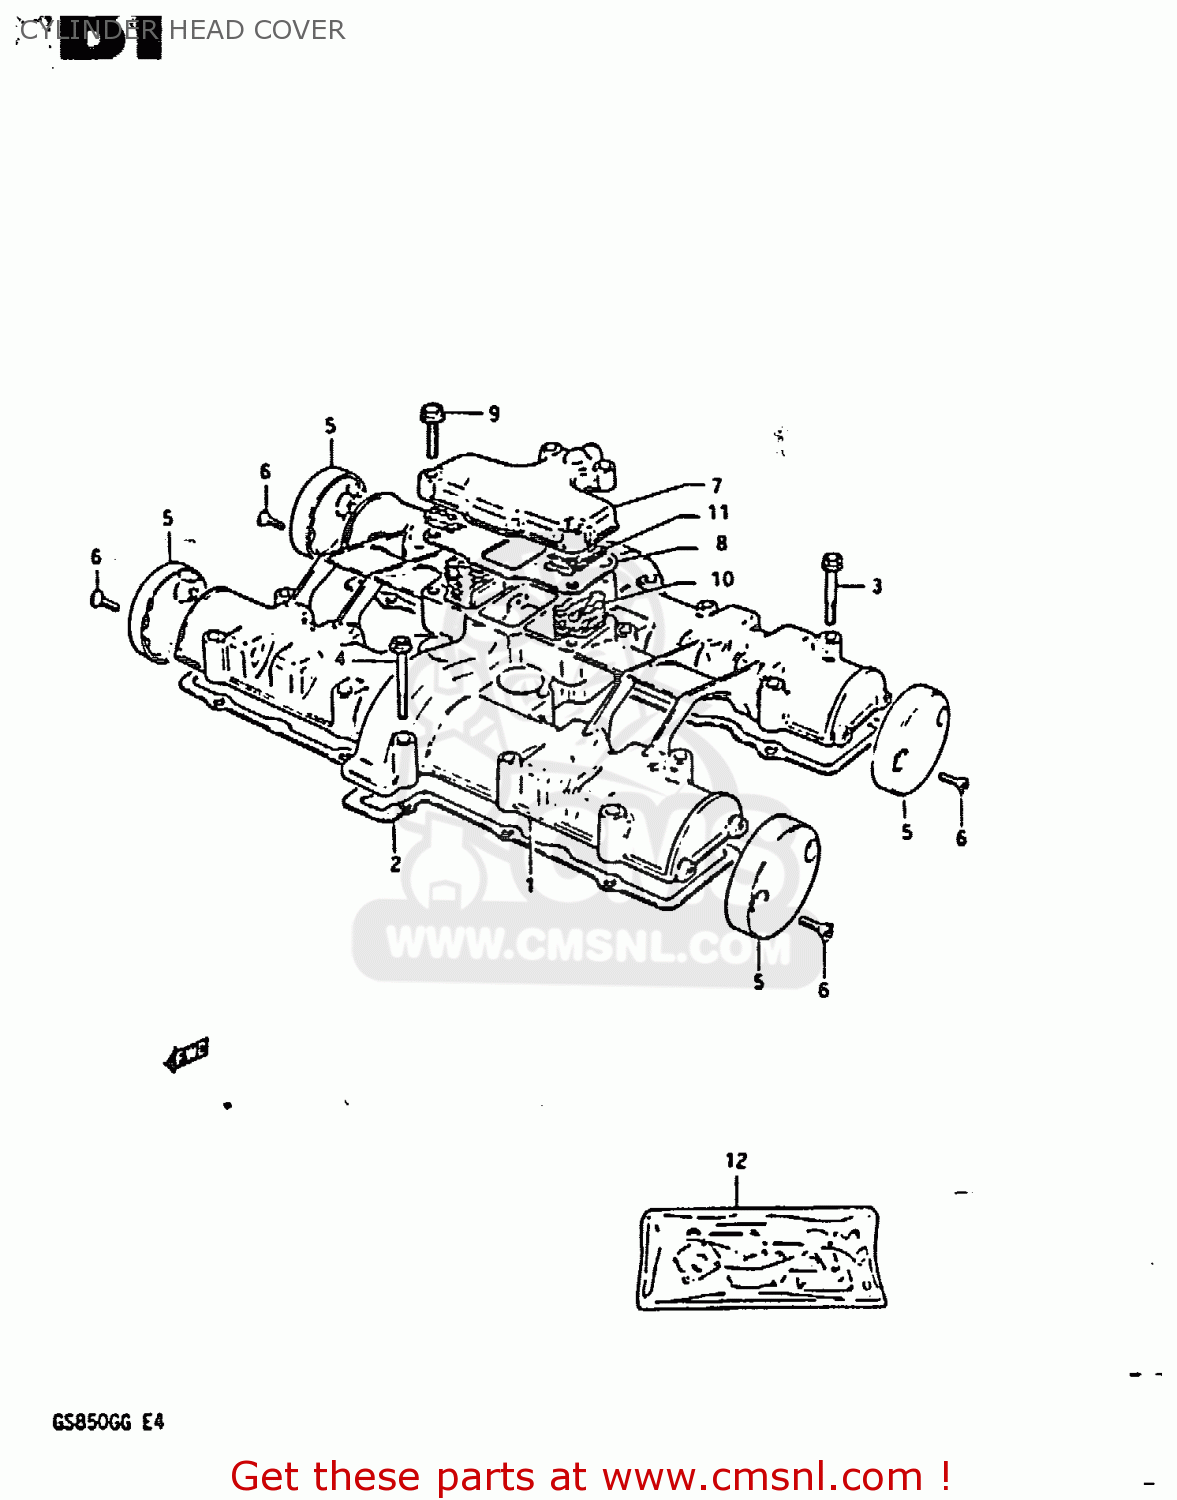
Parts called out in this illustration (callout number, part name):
1	COVER,CYLINDER
2	GASKET,CYLINDER HEAD COVER (MCA)
3	BOLT
4	BOLT (6X45)
5	CAP,CYLINDER HEAD COVER
6	SCREW(5X12)
7	COVER,BREATHER
8	GASKET (MCA)
9	BOLT
10	COVER,BREATHER
11	SEPARATOR,OIL BREATHER
12	GASKET SET (MCA)
